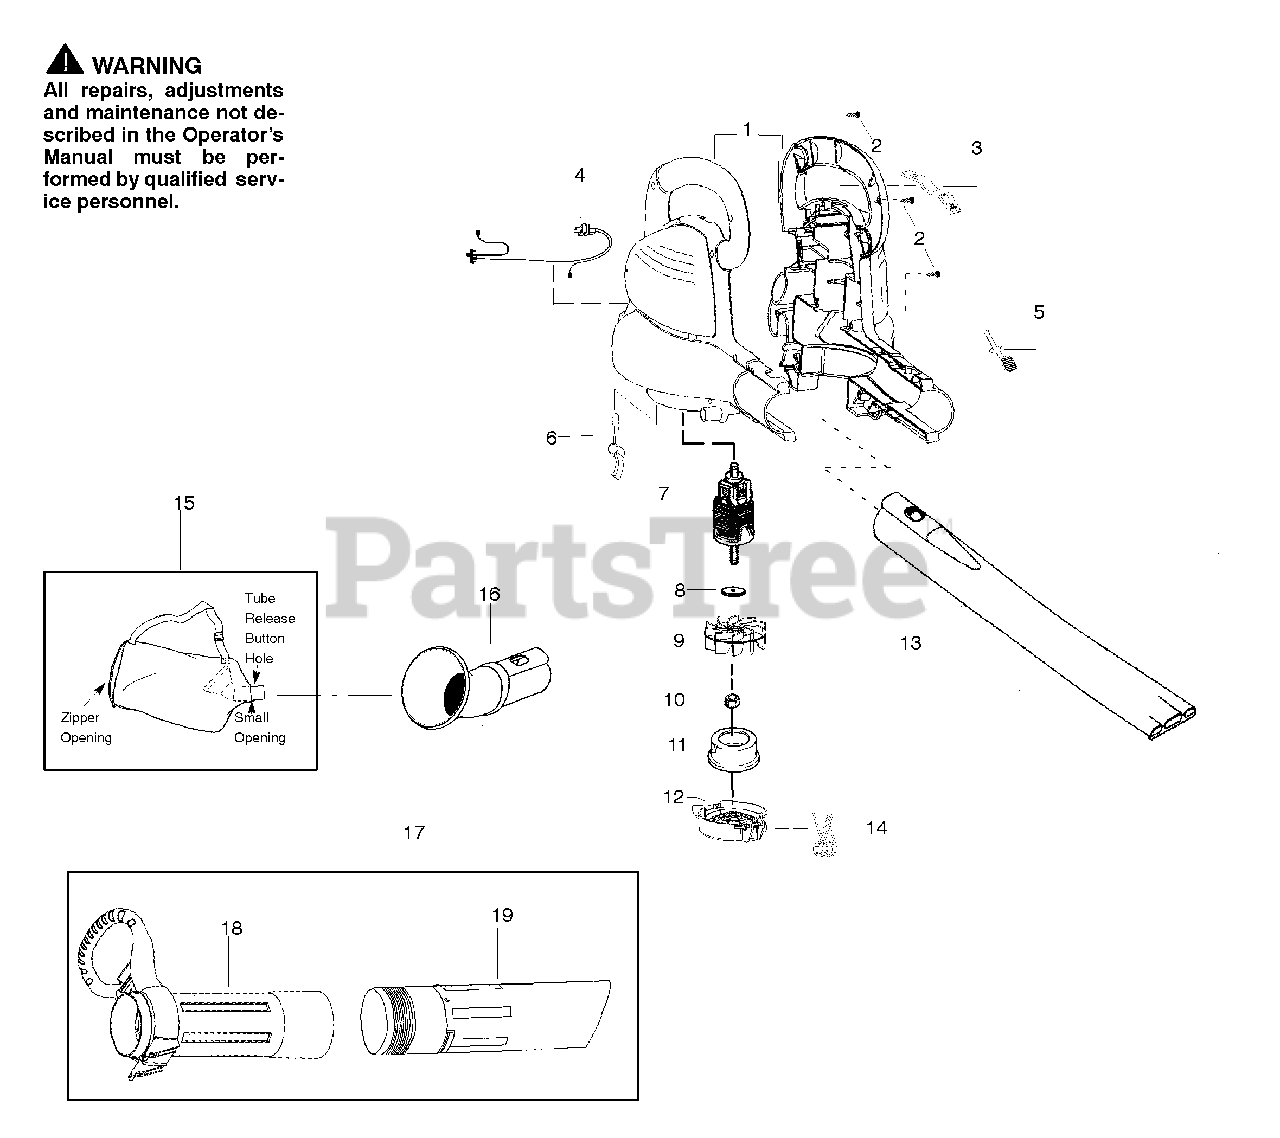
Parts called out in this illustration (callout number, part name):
1	Housing Set
3	Cover - Switch
4	Assy. Wiring Harness
5	Button - Tube Latch
6	Button - Door Latch
7	Assy. Motor
9	Impeller
10	Nut - Impeller
11	Restrictor - Inlet
12	Door - Vacuum Inlet
13	Tube - Blower
14	Spring - Door
15	Assy. - Vac Bag
16	Attachment-Vac Bag
17	Kit-Upper/Lower Tube w/handle
18	Tube - Upper Vac w/handle
19	Tube - Lower Vac
